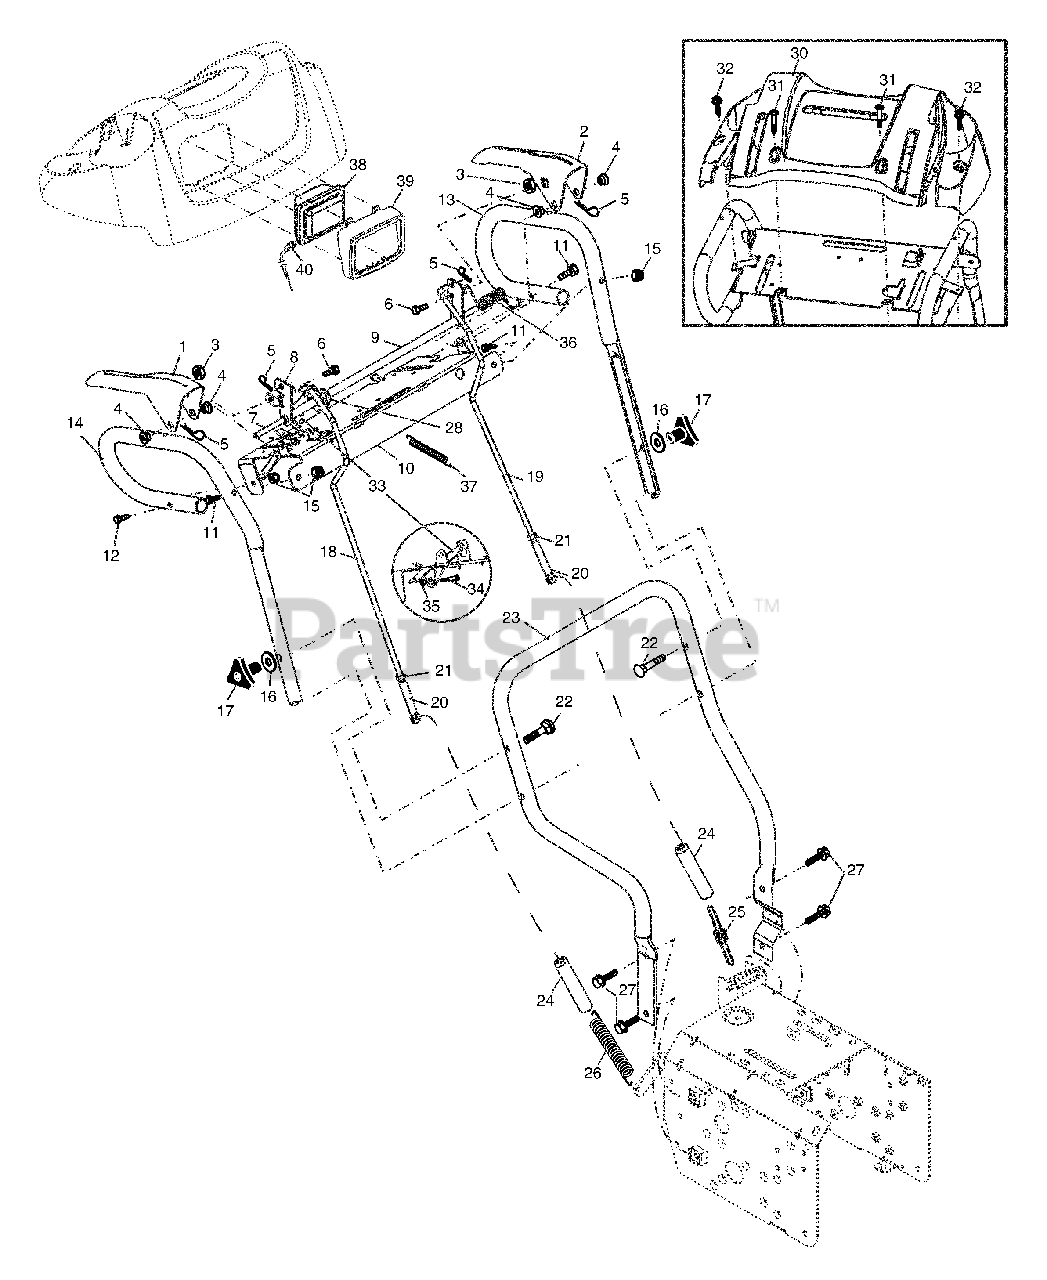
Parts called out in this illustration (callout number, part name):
1	Lever, Auger Control, RH
2	Lever, Traction Drive Control, LH
3	Nut, Cage 1/4-20
4	Bushing, Flange
5	Retainer, Hairpin
6	Screw, Hex Head 1/4-20 x 3/4
7	Rod, Interlock
8	Tube Assembly, Interlock, RH
9	Tube Assembly, Interlock, LH
10	Panel, Control
11	Screw, Hex Head 5/16-18 x 1-1/2
12	Screw, Hex Head 5/16-18 x 1-3/4
13	Handle Tube, LH
14	Handle Tube, RH
15	Nut, Lock 5/16-18
16	Washer, Flat 3/8
17	Knob, Handle
18	Rod, Auger Control
19	Rod, Traction Control
20	End, Control Rod
21	Nut, Hex, Jam 5/16-18
22	Bolt, Carriage 3/8-16 x 2-1/4
23	Handle Tube, Lower
24	Sleeve, Spring
25	Spring, Traction Drive
26	Spring, Auger Control
27	Screw, Hex Head 3/8-16 x 1
28	Clip, Panel
30	Console, Panel
31	Screw, Hex Head, Tapping #10-24 x 1-1/4
32	Screw, Hex Head, Tapping #10-24 x 1/2
33	Latch, Interlock
34	Bolt, Shoulder
35	Nut, Lock 1/4-20
36	Spring, Torsion
37	Spring, Interlock
38	Bezel, Light
39	Light
40	Wiring Harness, Light
